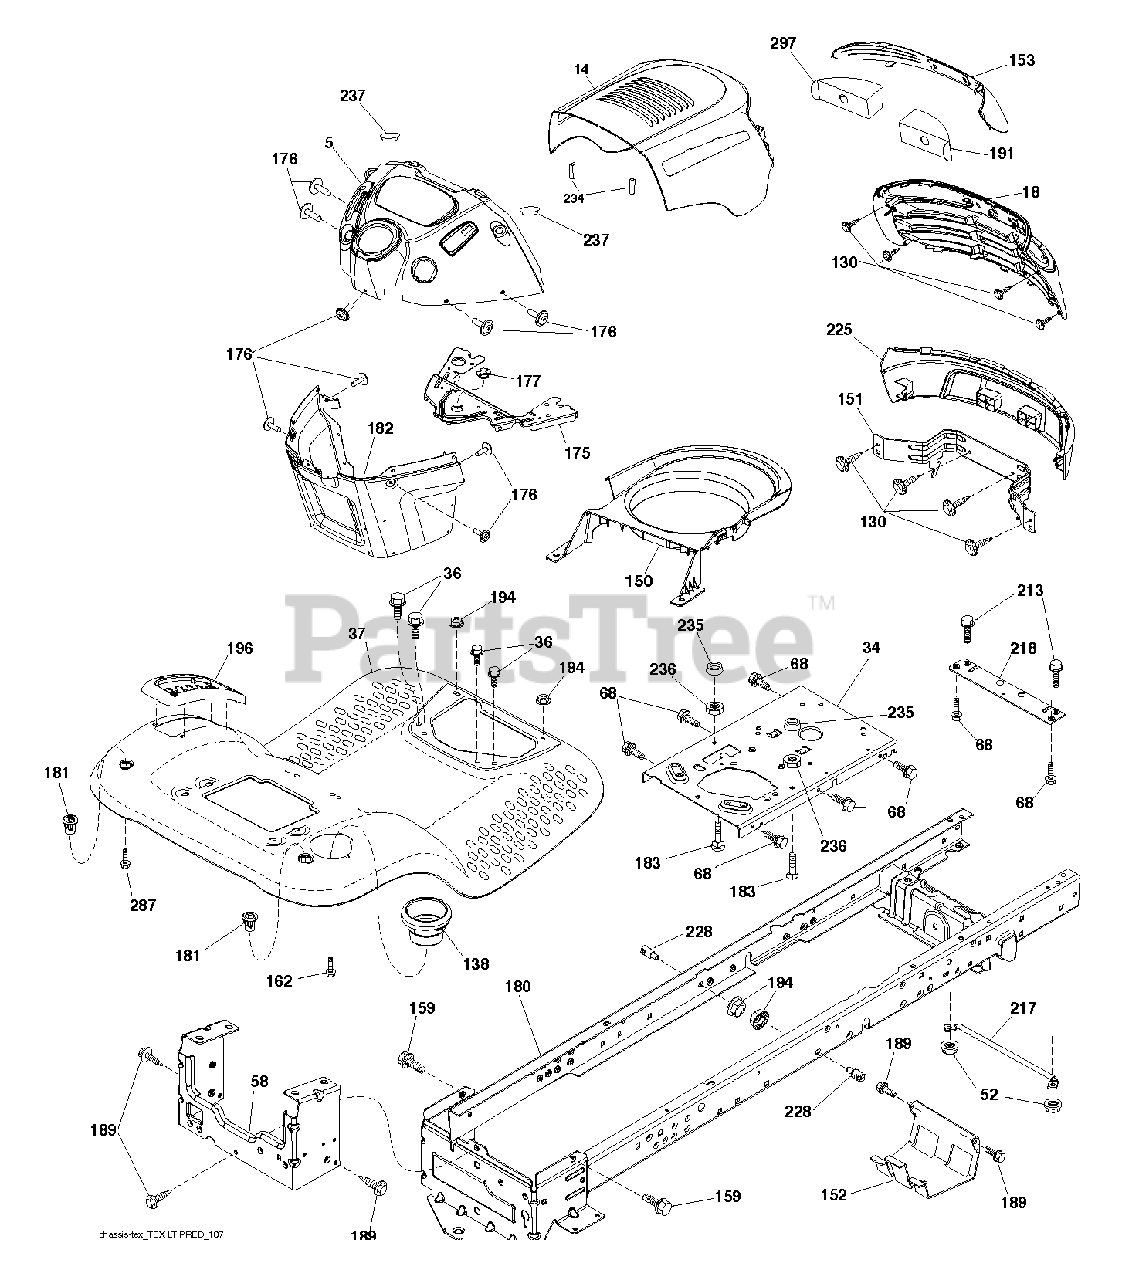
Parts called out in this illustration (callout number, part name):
5	DASH.PRED.LT.CC.ICY.N/SRV.BLK
14	HOOD.PREDATR.LT.U-FRM.TPVNT428
18	GRILL
34	PLATE.ENGINE.WELDED.CHASSIS
36	SCREW 5/16"
37	FENDER.TLT.W/CPH.428
52	LOCKNUT
58	DRAWBAR UPPER 2PC SMALL FENDER
68	SCREW LT
130	SCREW.#10 X 0.750.BOS (2 2)
138	CUPHOLDER.TL.TEX.BLACK
150	DUCT.AIR.TOP.VENT.PREDATOR.LT
151	BRACKET.PIVOT.ALPHA.LT
152	SHIELD.BROWNING.W/TEX
153	LENS.PREDATOR.LT
159	SCREW, 3/8-16X3/4
162	SCREW.HI-LO.CONSOLE
175	CROSSMEMBER
176	SCREW.#10-24X5/8.RN.QU
177	BUSHING STEERING
180	CHASSIS
180	CHASS.WLDMNT.TL.12GA/2P.48/54
181	FEND/FTRST.PCH.CPH.NFW
182	DASH.LOWER.PREDATOR LT
183	BOLT.5/16-18X1-1/4 FULL THD
189	SCREW
191	INSERT.REFLECT.PREDATOR.LT.RH
194	NUT LOCK HEX FLANGE 5/16-18
213	BOLT
217	ROD.PIVOT.HOOD
218	X-PIECE.HOOD.STOP.NON/
228	STUD.FASTNER.W/ANTI-ROTATE
234	BUMPER.HOOD.TEX.HUSQVARNA
235	SPACER FENDER
236	NUT.CENTERLOCK.5/16-
237	PLUG.MOUNT.CARGO.BLK
287	SCREW 1/4X20
297	REFLECTOR.INSERT.PRED.LH.LT
